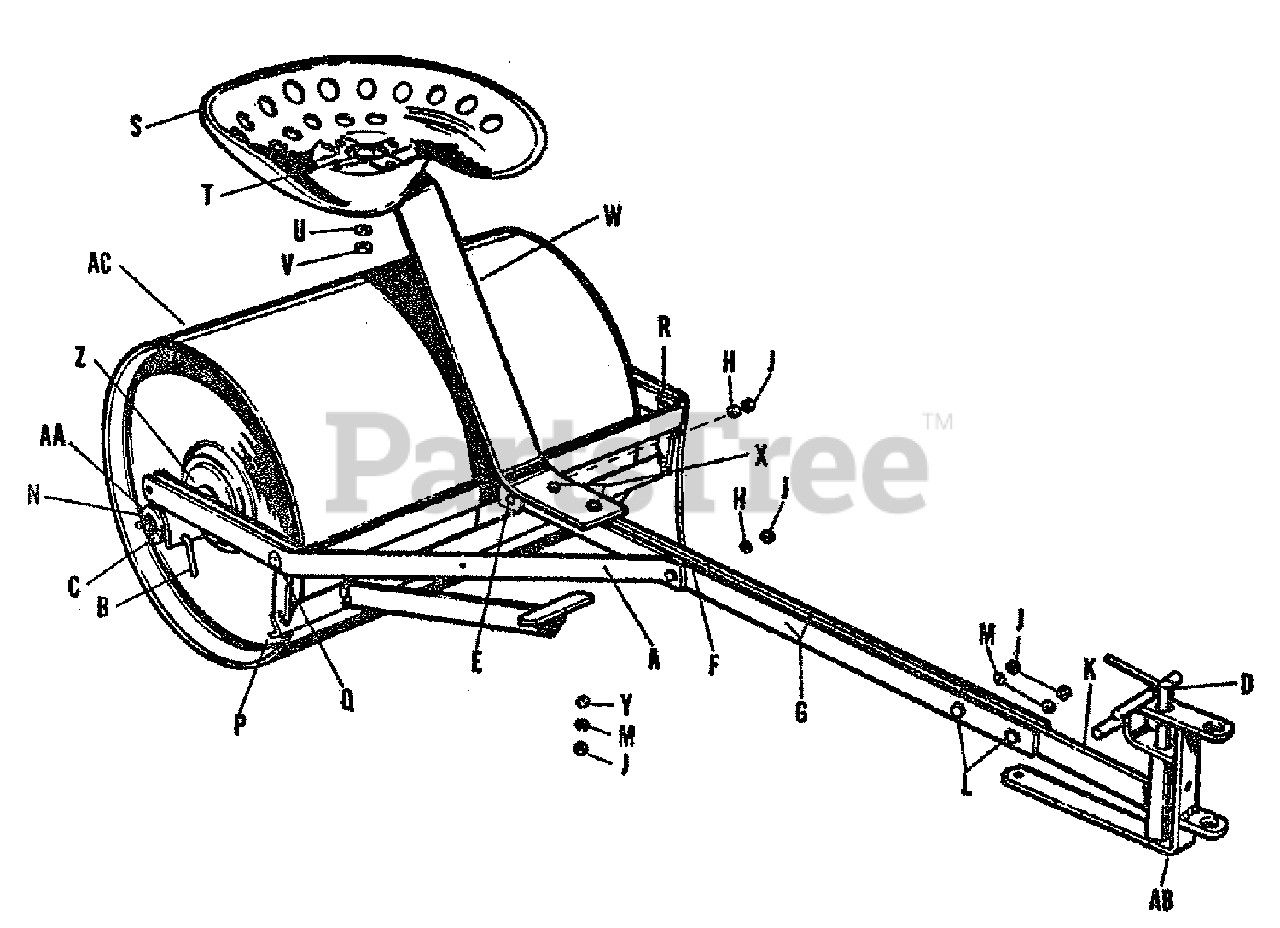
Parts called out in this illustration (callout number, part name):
A	FRAME ASSEMBLY
C	CLIP SPRING
D	HITCH PIN ASSEMBLY
E	SCREW, Hexagon Head Cap 3/8"-16 N.C. x 2" Large
F	WASHER, Plain 1,2"
H	WASHER, Plain 1,2"
J	NUT, Hexagon Full 3/8"-16 N.C.
K	PIVOT ASSEMBLY
L	SCREW, Hexagon Head Cap 3/8"-16 N.C. x 1-1/2" Large
M	WASHER, Lock 3/8" Regular
N	PIN, Cotter
P	BRAKE ASSEMBLY
R	PIN, Cotter
S	SEAT, Pan
T	BOLT, Carriage 1/2"-13 N.C X 1" Large Short Neck
U	WASHER, Lock 1/2" Regular
V	NUT, Hexagon Full 1/2"-13 N.C.
W	SUPPORT SEAT
X	SCREW, Hexagon Head Cap 3/8"-16 N.C. x 2-1/4" Large
Y	WASHER, Plain 3/8" Regular
Z	WASHER, Plain
AA	ROLLER BEARING ASSEMBLY
AB	FRAME EXTENSION ASSEMBLY
AC	LAWN ROLLER
